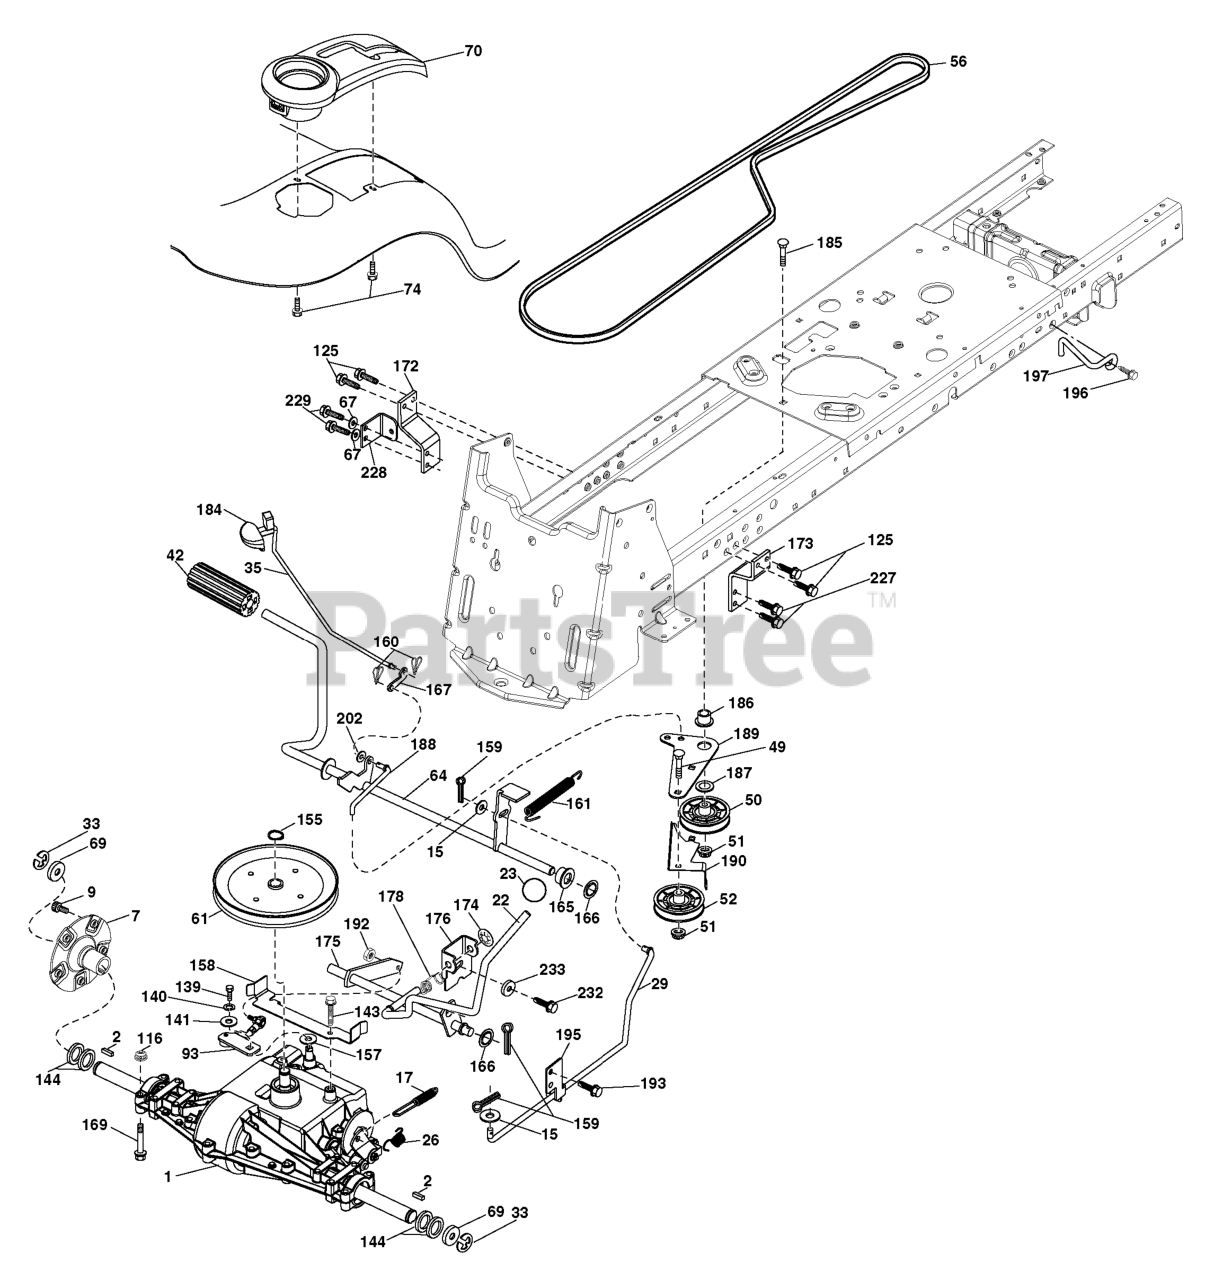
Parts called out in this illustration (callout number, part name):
2	Key 1/4 x 2.5
7	Hub Asm. Wheel Rear
9	Bolt Hub Wheel Rear
15	Washer 13/32 x 13/16 x 16 Ga.
17	Spring, Brake
22	Shift Shaft Asm.
23	Knob
26	Spring Brake Return
29	Rod, Brake
33	Ring E #5133-100
35	Rod, Brake, Park
42	Cover, Foot Pedal
49	Bolt
50	Pulley Idler Flat
51	Lock Nut 3/8-16
52	Idler V-Groove 910" Offset
56	V-Belt, Drive
61	Pulley Transaxle
64	Shaft Asm. Pedal Brake Control
67	Washer 13/32 x 13/16 x 12 Ga.
69	Washer
70	Console
74	Screw 1/4 x 1/2
93	Link Shift
116	Nut Lock Hex Flange 5/16-18
125	Screw 5/16-18 x 3/4
139	Bolt 1/4-28
140	Washer Lock Hvy Helical
141	Washer 9/32 x 3/4 x 10
143	Screw 5/16-18 x 1/2
144	Washer Spacer Axle
155	Ring Retainer
157	Washer Plate
158	Belt Keeper
159	Pin Cotter 1/8 x 3/4
160	Retainer Clip
161	Spring, Return, Clutch
165	Busing Shaft Brake Hand Control
166	Nut Push .625
167	Latch Brake Parking
169	Bolt 5/16-18 x Gr. 5
172	Strap Torque LH
173	Torque Strap RH
174	Nut Push
175	Shaft Asm. Shift Gear Drive
176	Arm Clevis Rod Shift
178	Spring Shift
184	Handle Parking Brake
185	Bolt
186	Spacer Retainer
187	Washer
188	Link Clutch Ground Drive
189	Bellcrank Ground Drive
190	Keeper Bellcrank Ground Drive
192	Nut Lock Center 1/4-28
193	Screw 5/16-18 x 3/4
195	Bracket Brake Rod
196	Screw 3/8-16 x 1
197	Bracket Anti-Rotation Clutch
202	Washer
228	Bracket Anti-Sway
229	Screw 5/16-18 x 1
232	Bolt 7/16-14 x 1 Gr. 5
233	Washer Serrated
